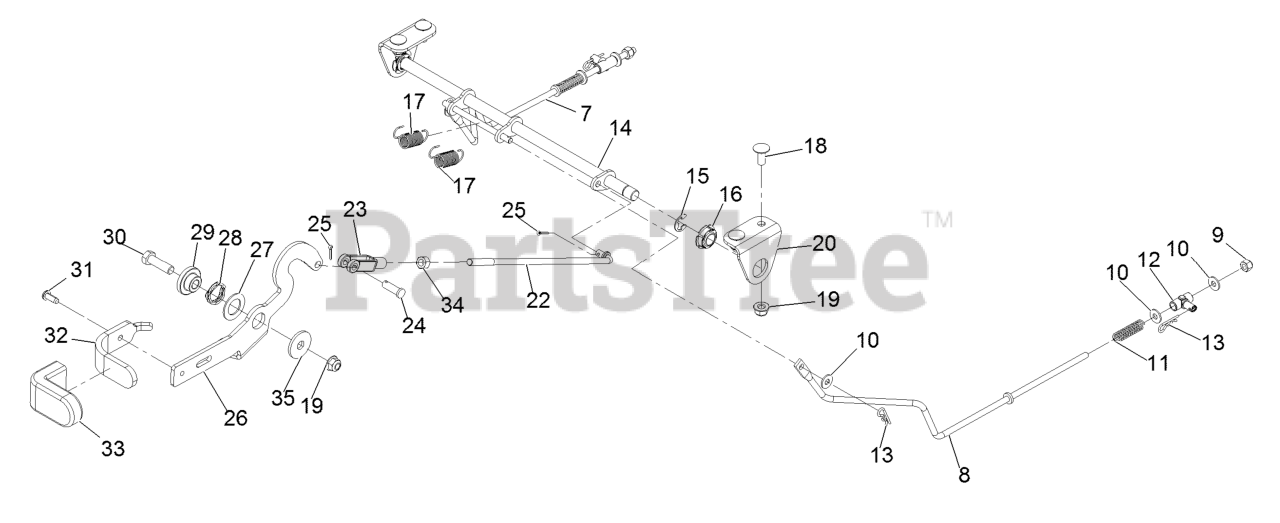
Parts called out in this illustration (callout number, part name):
7	Rod-Brake, RH
8	Rod-Brake, LH
9	Nut-Nyloc 1/4-20
11	Spring-Compression
12	Mount-Pivot
13	Pin-Cotter
14	Pivot-Brake
15	Ring-Retaining
16	Bearing-Spherical
17	Spring-Extension
18	Bolt-Carriage 5/16-18 X 3/4 Short Neck
19	Nut-Nyloc 5/16-18 Flg
20	Angle-Mount Pivot
22	Rod-Link Handle
23	Yoke-Adjustable
24	Pin-Clevis 5/16 X 1 49/64
25	Pin-Cotter 3/32 X 1/2
26	Lever-Brake
27	Washer-Thrust
28	Washer-Wave
29	Pivot-Flange
30	Screw-HH 3/8-16 X 1 1/4
31	Screw-Button Head 1/4-20 X .62 Tf
32	Handle-Brake
33	Grip-Lever
34	Nut-Hex 5/16-24
35	Washer
